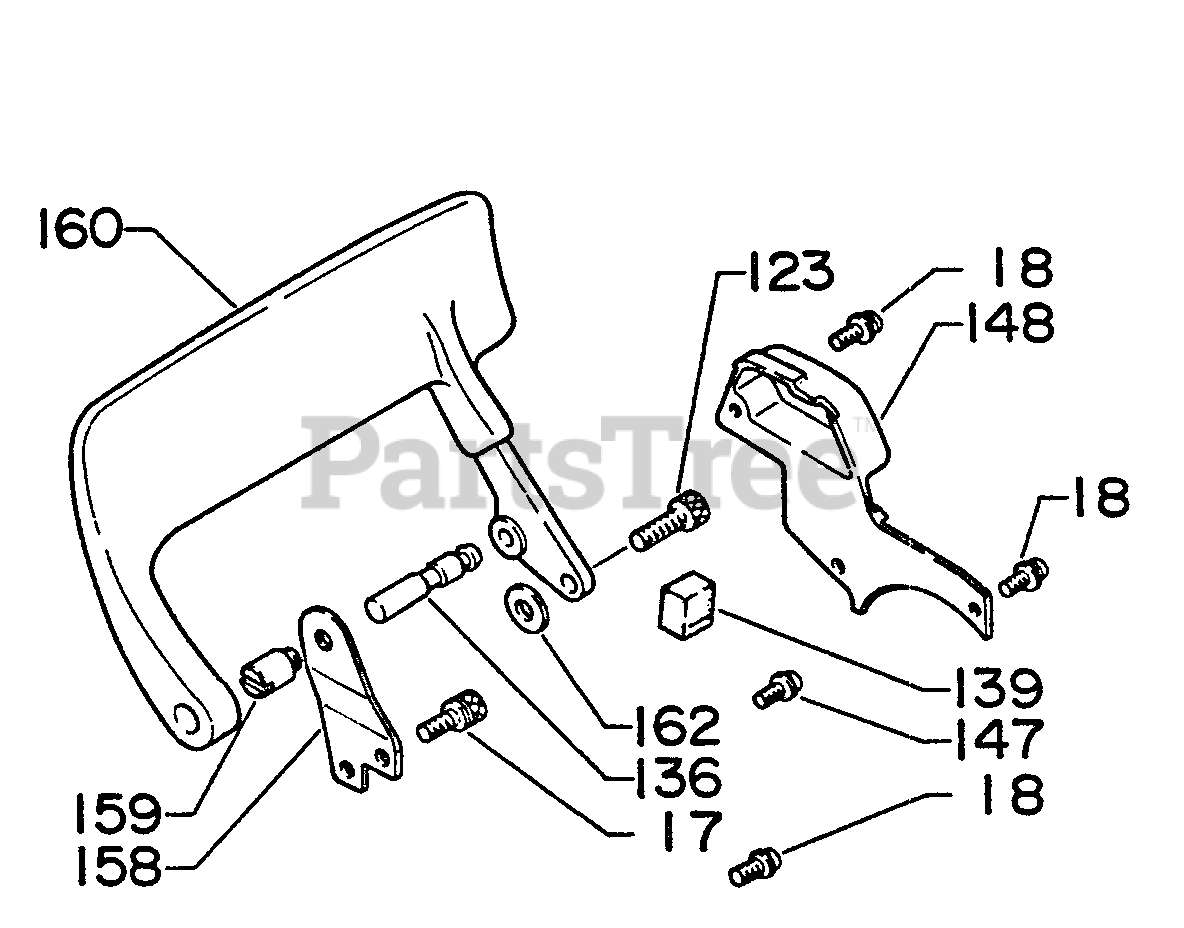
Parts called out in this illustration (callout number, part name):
17	SCREW - 5X15
18	SCREW - 4X12
123	SCREW - 6X20
135	COVER, BRAKE
139	SEAL, DUST
147	SCREW - 5X14
148	COVER, BRAKE
161	SCREW - 6X20
162	WASHER - 6.5
